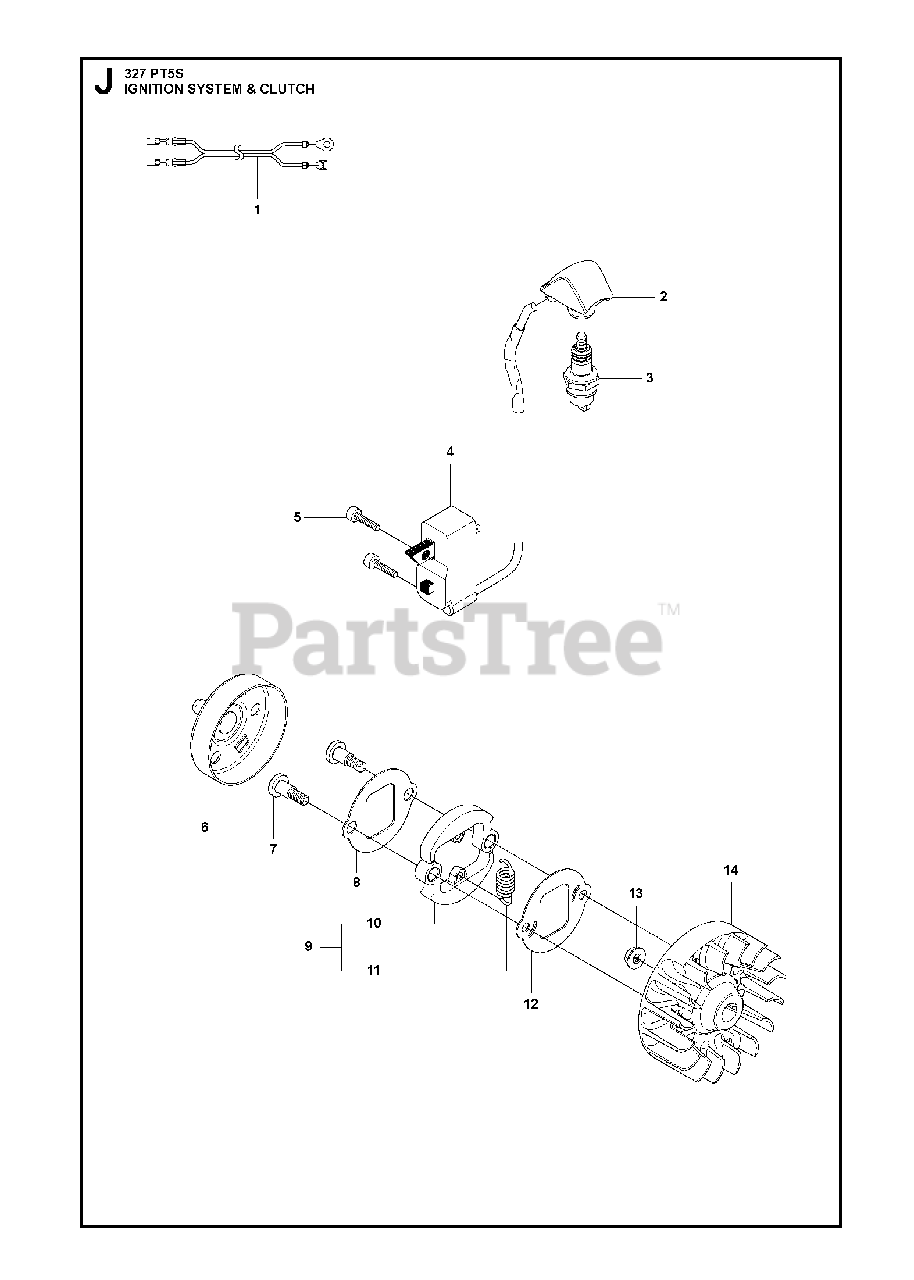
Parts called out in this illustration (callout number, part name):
1	SHORT CIRCUIT CABLE
2	SPARK PLUG CAP
3	Spark Plug, RCJ6Y
4	IGNITION MODULE OPS
6	CLUTCH DRUM
8	WASHER, CLUTCH
10	CLUTCH
11	SPRING
13	FLANGE NUT
